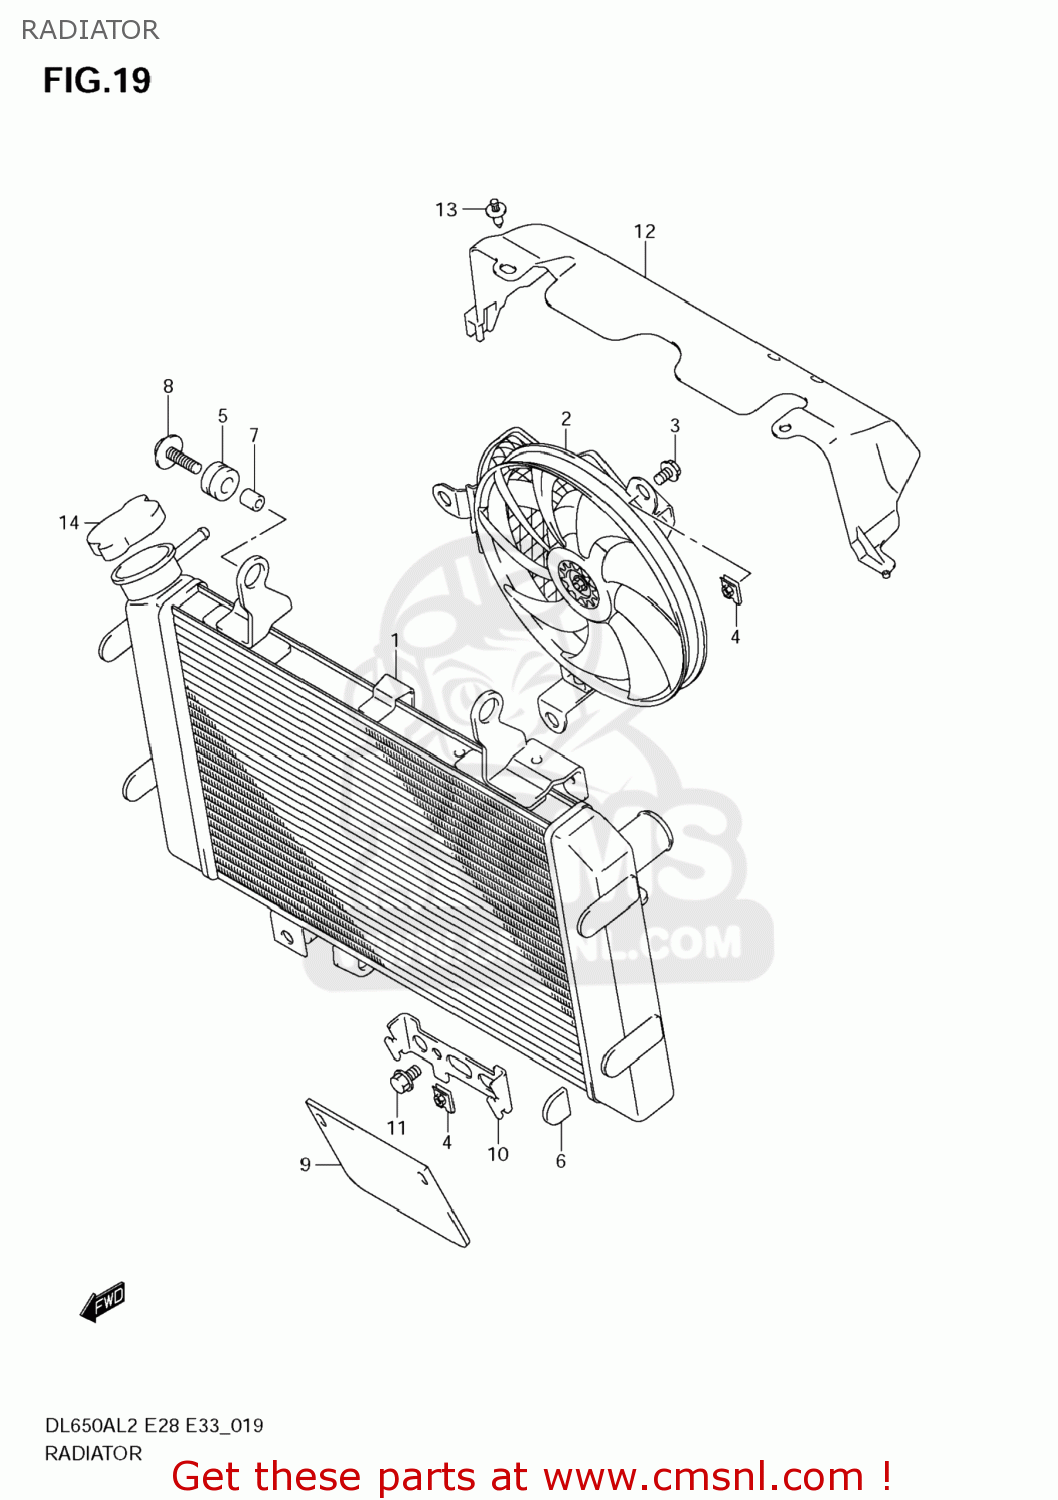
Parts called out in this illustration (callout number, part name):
1	RADIATOR ASSY,WATER
2	FAN ASSY,RADIATOR
3	BOLT,FAN ASSY
4	NUT,FAN ASSY
5	CUSHION
6	CUSHION
7	SPACER(6.5X10X10)
8	BOLT(6X25)
9	RUBBER,RADIATOR UNDER
10	BRACKET,RADIATOR UNDER RUBBER
11	BOLT
12	SHIELD,RADIATOR HEAT
13	CLIP(BLACK)
14	CAP,RADIATOR
